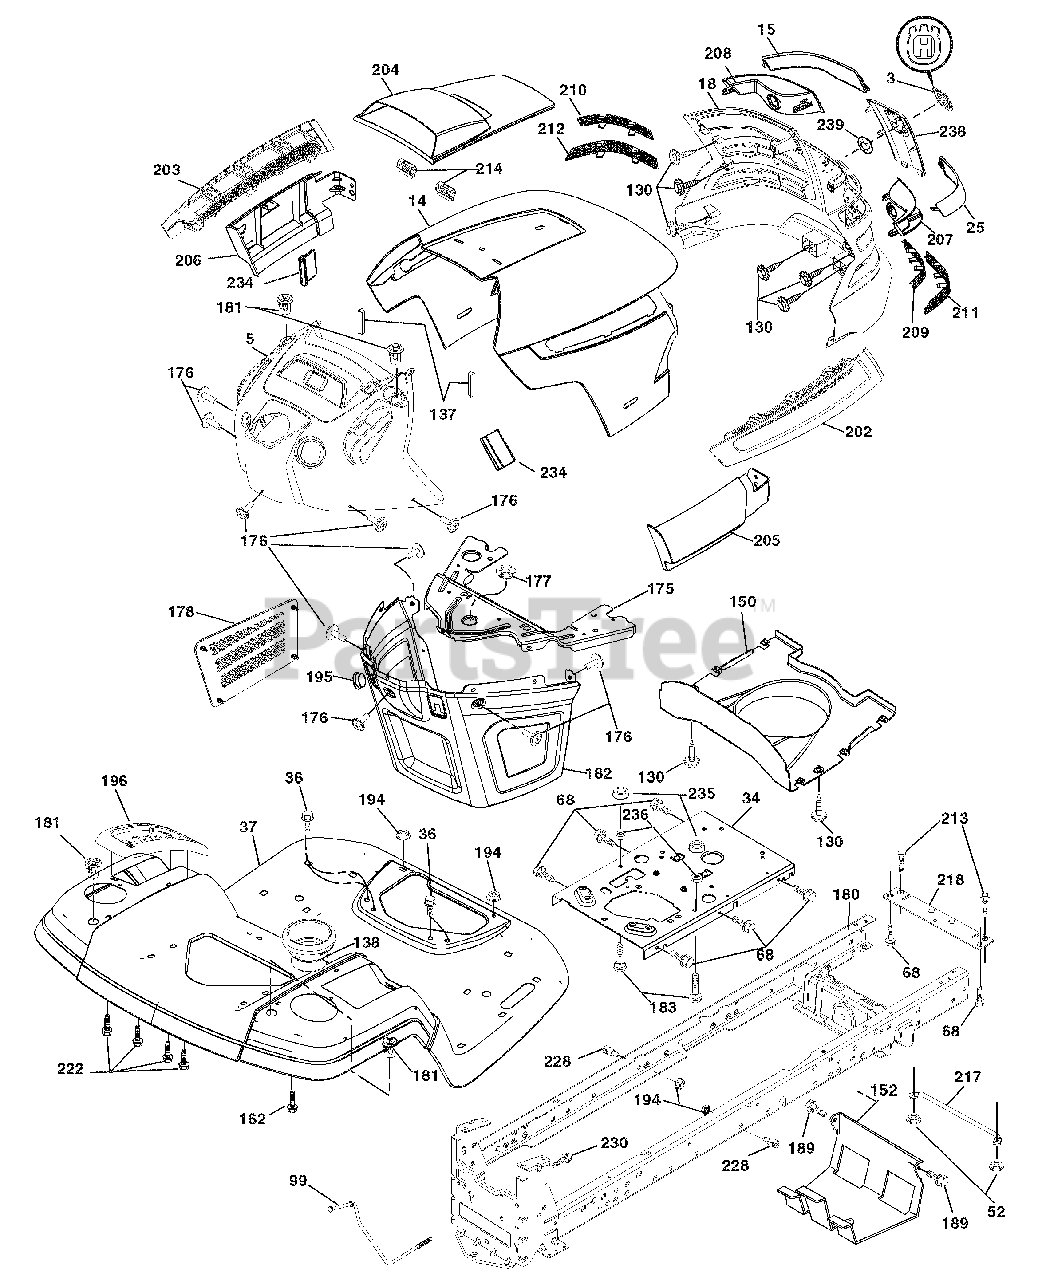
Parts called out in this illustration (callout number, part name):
3	Logo
4	Logo
14	Hood
18	Grille/Lens Asm.
34	Plate Engine
36	Screw 5/16-18 x 3/4
37	Fender
52	Nut Lock 5/16-18
68	Screw Thdrol 5/16-18 x 1/2
99	Rod Asm Bypass
130	Screw 10 x 3/4 Single Lead-Hex
137	Bumper Dash
138	Cupholder
152	Shield Browning
175	Crossmember
176	Screw 10-24 x 5/8
177	Bushing Steering
178	Cargo Net Asm.
180	Chassis
181	Bushing Mtg. Fender Crgo
182	Dash Lower
183	Bolt Fin Hex 5/16-18 unc x 1-1/4
189	Screw 5/16-18 x 3/4
194	Nut Lock Hex Flange 5/16-18
195	Plug Hole Dash Lower
196	Console Asm. Deck Lift
202	Vent Side Hood RH
203	Vent Side Hood LH
204	Vent Top Hood
205	Skirt Hood Side RH
206	Skirt Hood Side LH
209	Insert Hex Top RH
210	Insert Hex Top Lh
211	Insert Hex Bottom RH
212	Insert Hex Bottom LH
213	Bolt 5/16-18 x 3/4
214	Clip Retainer Tinner
217	Rod Pivot
218	X-Piece Hood Stop
222	Screw Thdrol 1/4-20 x 5/8
228	Stud Fastner
230	Bolt Shoulder 5/16-18
234	Bumper Hood
235	Spacer Fender
236	Nut Lock 5/16-18 UNC
